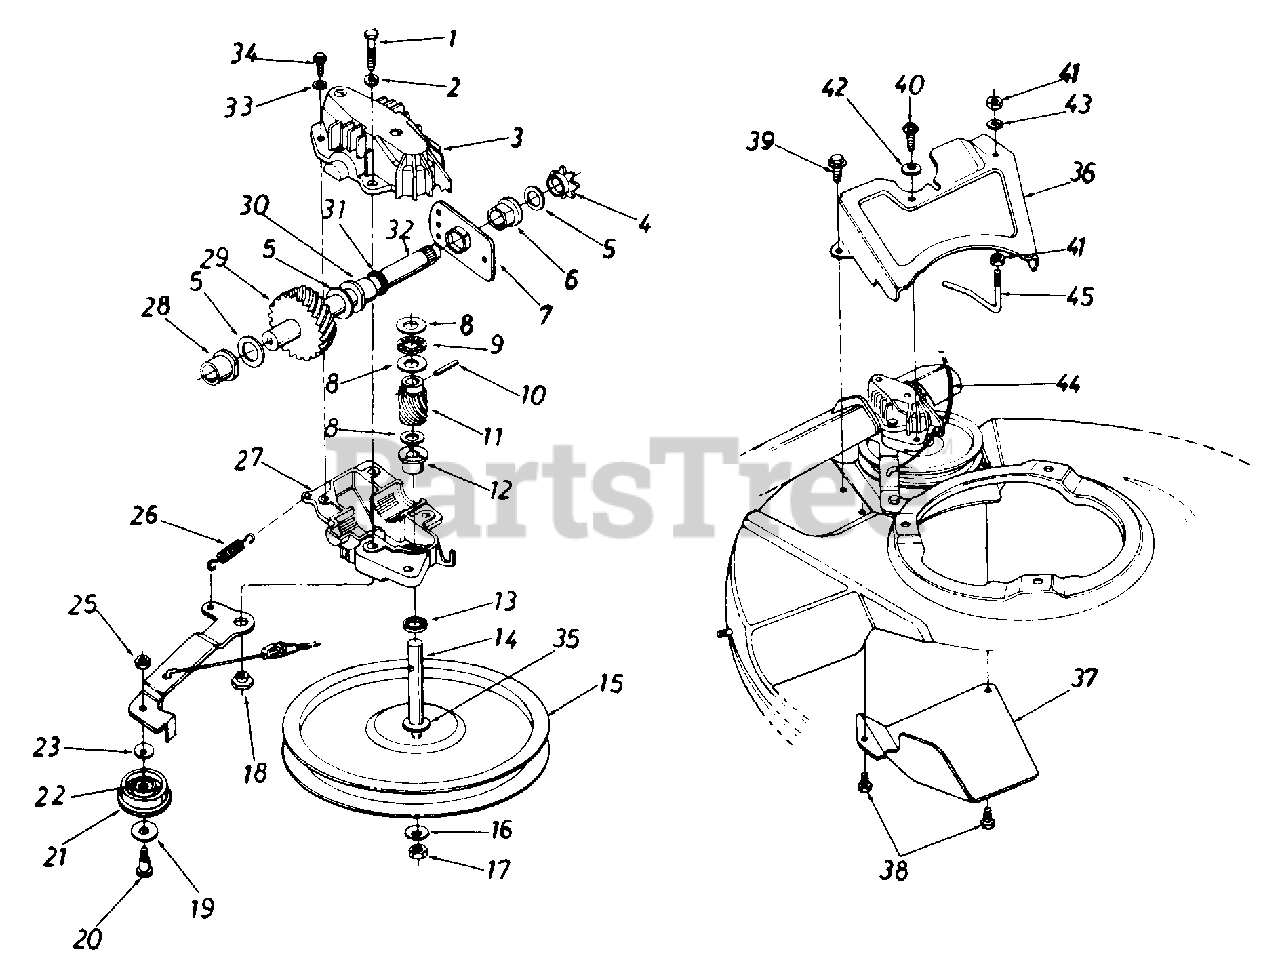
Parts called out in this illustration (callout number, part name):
1	SCREW-HEX 1/4-20 X 1.25
2	LOCK WASHER 1/4 DIA
3	HOUSING HALF-UPPER
4	SPROCKET-7T
5	WASHER-FL
6	BEARING-HEX FLANGE
7	BEARING-CUP HEX
8	WASHER-THRUST.382 X .684
9	BEARING-THRUST
10	PIN-SPRING-SPIR 1/8 X .625
11	GEAR-WORM
12	BEARING-FLANGE
13	SEAL-OIL-.375 ID
14	KIT-TRAN PUL SHFT
15	PULLEY
16	WASHER-SPRING BELL
17	NUT-HEX 1/4-28
18	SPACER-SHLD
19	WASHER-FL .995 X .032
20	SCREW-SHLD
21	KIT-PULLEY
22	BEARING-NEEDLE
23	WASHER-SPRING BELL
25	NUT-HEX 1/4-28
26	SPRING-EXTENSION
27	HOUSING HALF-LOWER
28	BEARING-FLANGE
29	SHAFT-ASSY W/GEAR
30	BEARING-FLANGE
32	SHAFT-ASSY W/GEAR
33	WASHER-LOCK-#10
34	SCREW-HEX WASH HD TAP
35	WASHER-HEX
36	GUARD-BELT
39	SCREW-HEX WASH SF TAPP
40	SCREW-HEX B-TAP 1/4-.62
41	NUT-HEX 1/4-20
42	WASHER-SPRING BELL
43	LOCK WASHER 1/4 DIA
44	CABLE-CLUTCH X 50.0
45	GUARD-BELT
